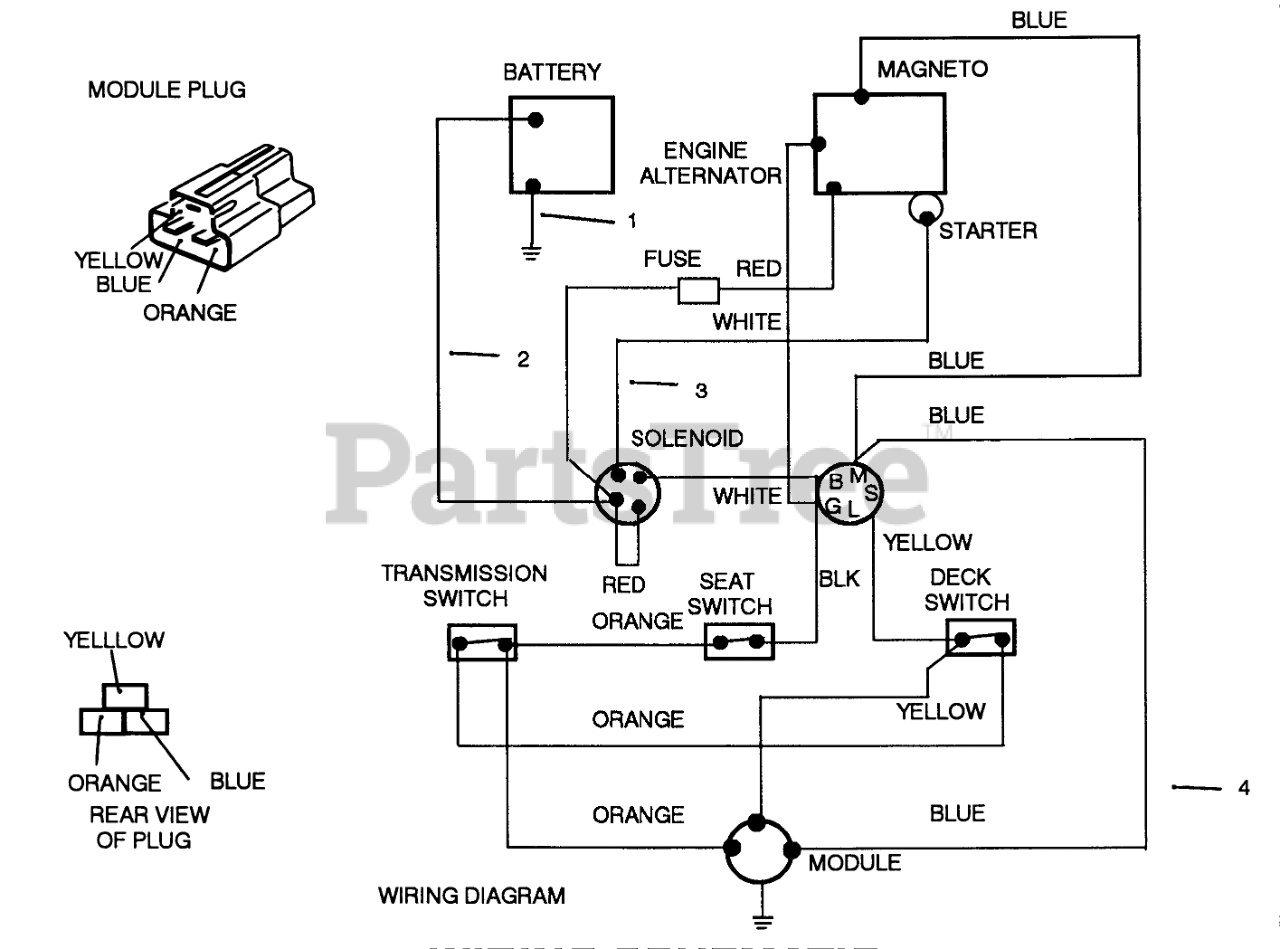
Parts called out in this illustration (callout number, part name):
1	WIRE ASM
2	WIRE ASM(BATT/GRD.
3	WIRE HARNESS
4	WIRING HARNESS
